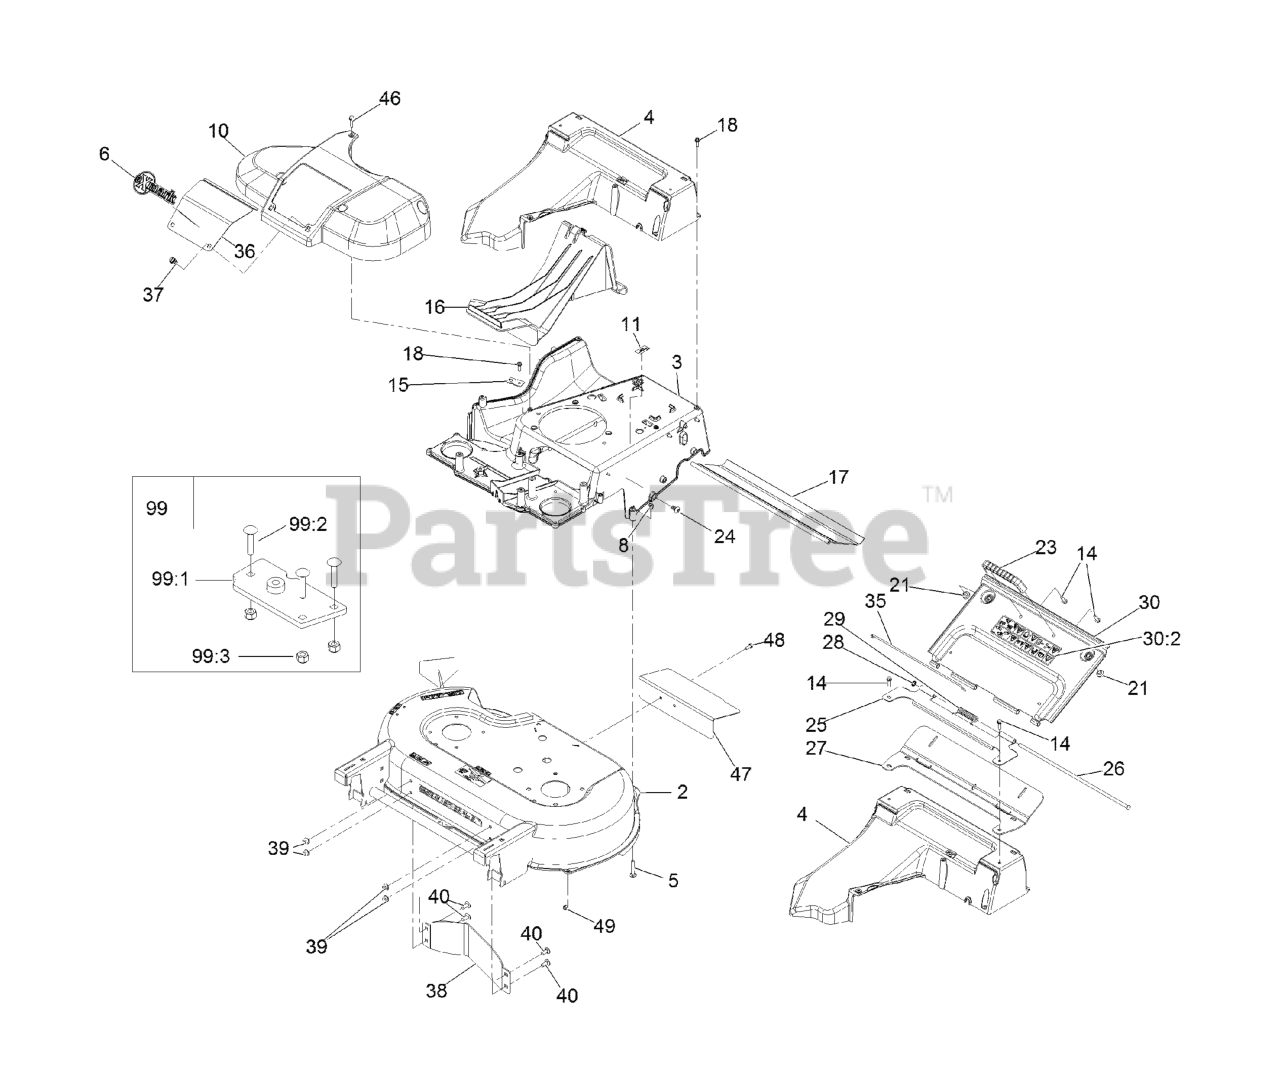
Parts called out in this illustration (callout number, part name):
2	DECK-30, W/DECALS
3	FRAME
5	BOLT-CAR
6	DECAL-EXMARK LOGO
8	NUT-LOCK, NI
10	COVER-BELT
11	Decal-Patent Ttco.Com
14	SCREW-HWH
15	BRACKET-CABLE, TRACTION
16	PLUG-MULCH
17	SHIELD-TRAILING
18	SCREW-HWHTF
23	HANDLE-DOOR
24	SCREW-PTH
25	BRACKET-HINGE
26	PIN-HINGE
27	SEAL-DOOR
28	RING-RETAINING
29	SPRING-TORSION, COVER
30	REAR DOOR ASM
30:2	DECAL-WARNING
35	CLIP-SEAL
36	DOOR-ACCESS
37	FASTENER
38	BAFFLE-CONTROL
39	NUT-HF, NI
40	SCREW-HSBH
46	SCREW-HWHTF
47	DEFLECTOR-REAR
48	SCREW-HWH
49	NUT-LOCK, NI
99	FRAME PLATE KIT
99:1	PLATE-FRAME
99:2	SCREW-CARR
99:3	NUT-LOCK, NI
